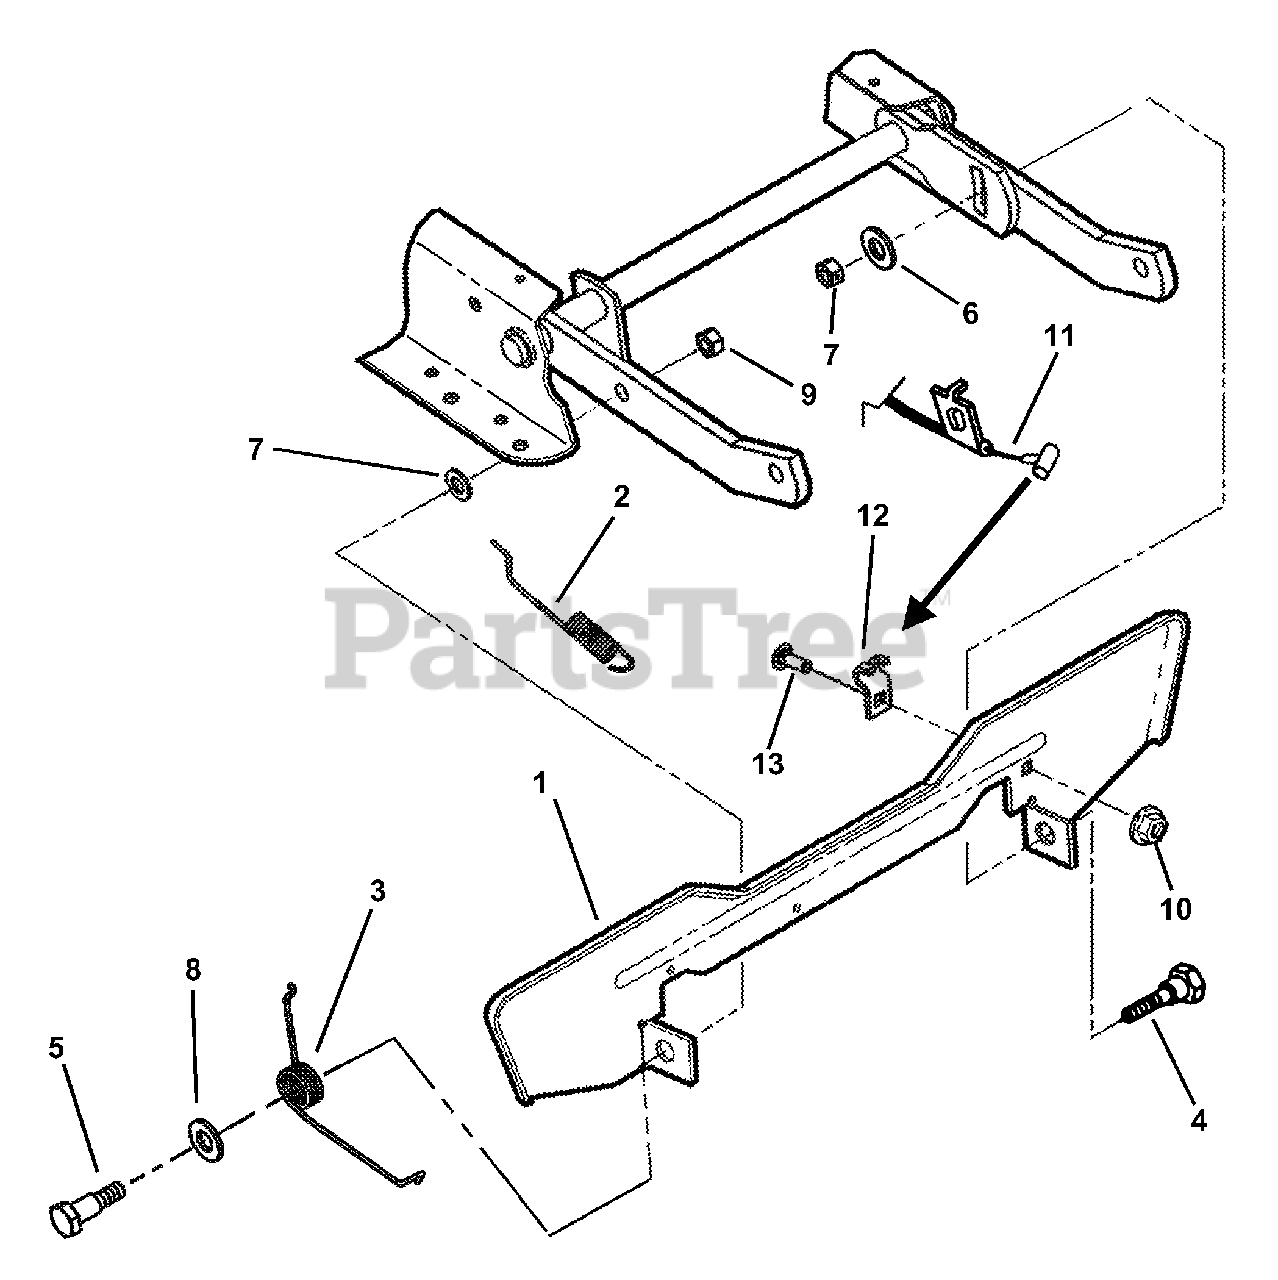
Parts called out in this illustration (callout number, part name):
1	PEDAL, Blade Stop Control
2	SPRING, Latching
3	SPRING, Pedal
4	BOLT, 3/8-24 Shoulder, Grade 5
5	BOLT, 3/8-24 x 9/16" Shoulder
6	WASHER, Cone 13/32" I.D.
7	NUT, 3/8-24 Hex, Grade B
8	WASHER, 1/2" Flat
9	NUT, 3/8-24 Hex Center Lock
10	NUT, 1/4-20 Hex Flange Lock, Grade 5
11	CABLE, No Reverse In Mow
12	CLIP, Cable
13	BOLT, 1/4-20 x 3/4" Square Neck Carriage, Grade 5
